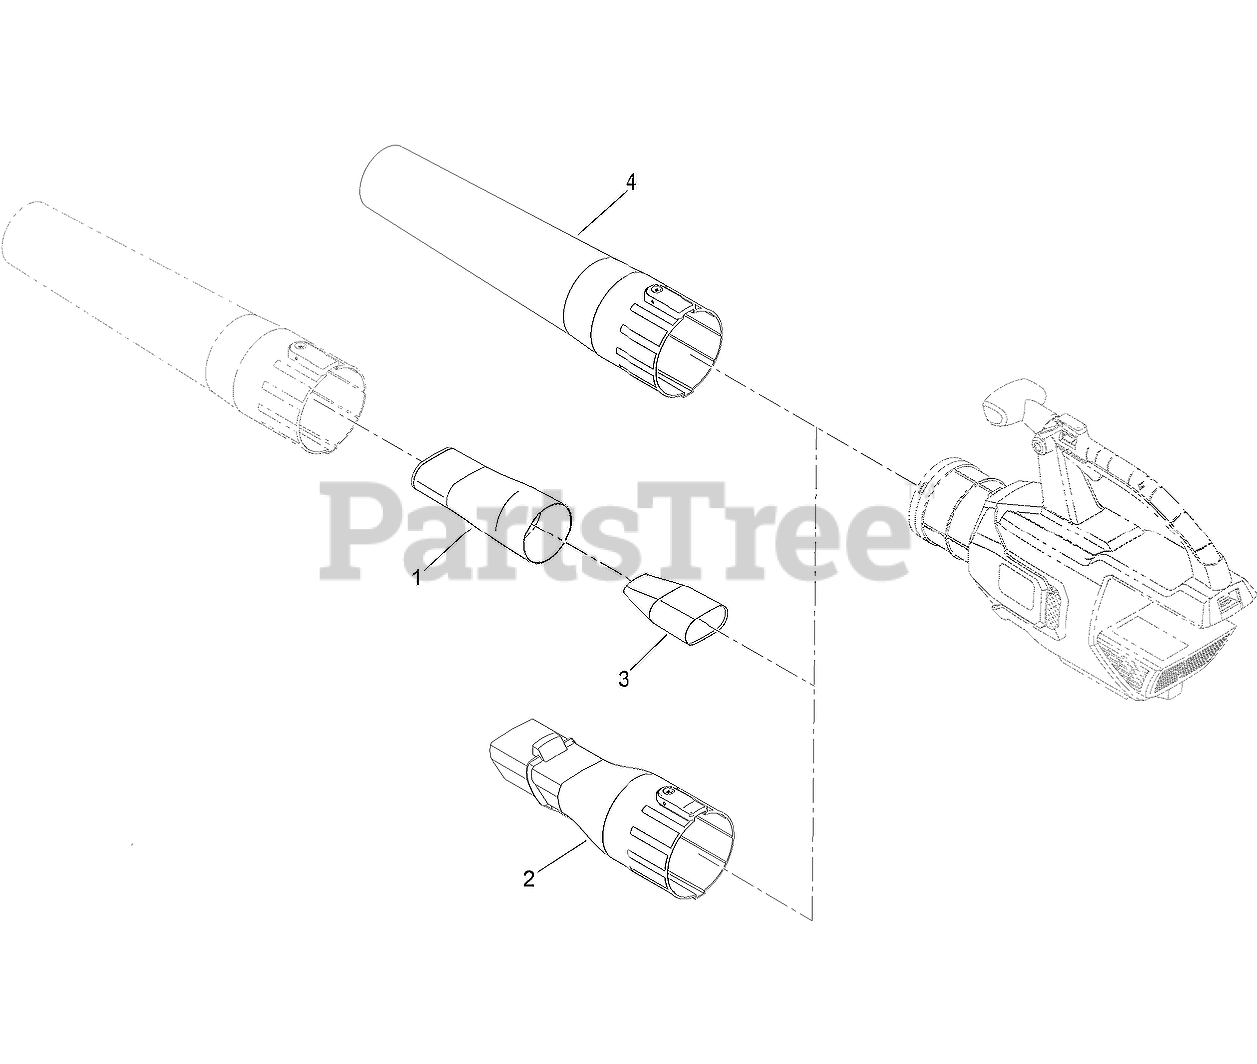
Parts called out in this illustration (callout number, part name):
1	ADAPTER-OSCILLATOR, MPH
2	ADAPTER-CLEANER, GUTTER
3	ADAPTER-INSERT, MPH
4	TUBE-BLOWER
